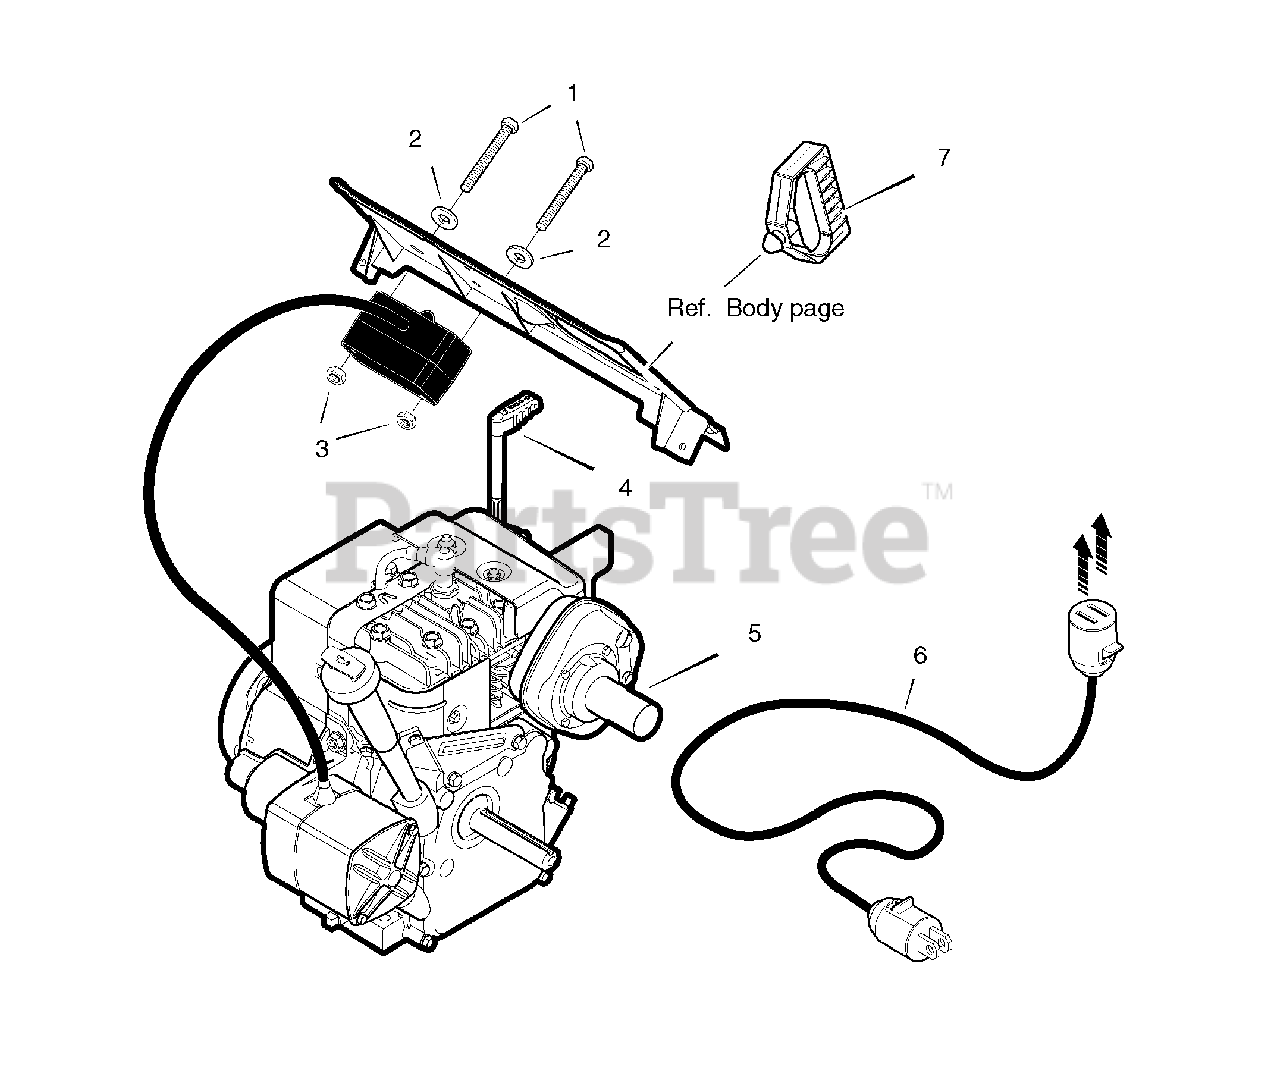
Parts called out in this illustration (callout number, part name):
1	SCREW, No. 8-32 x 3.00
2	WASHER, FLAT No. 8
3	NUT, Keps No. 8
4	LEVER, Choke *
5-1	Muffler *
5-2	GASKET, Muffler *
5-3	Bolt, Muffler *
5-4	WASHER, Split Lock
5-5	NUT, Hex 5/16-18
5-6	BOLT, Hex 5/16-18
6	CORD, Electric 110V
6	CORD, Electric 220V
7	GRIP, Mitten
